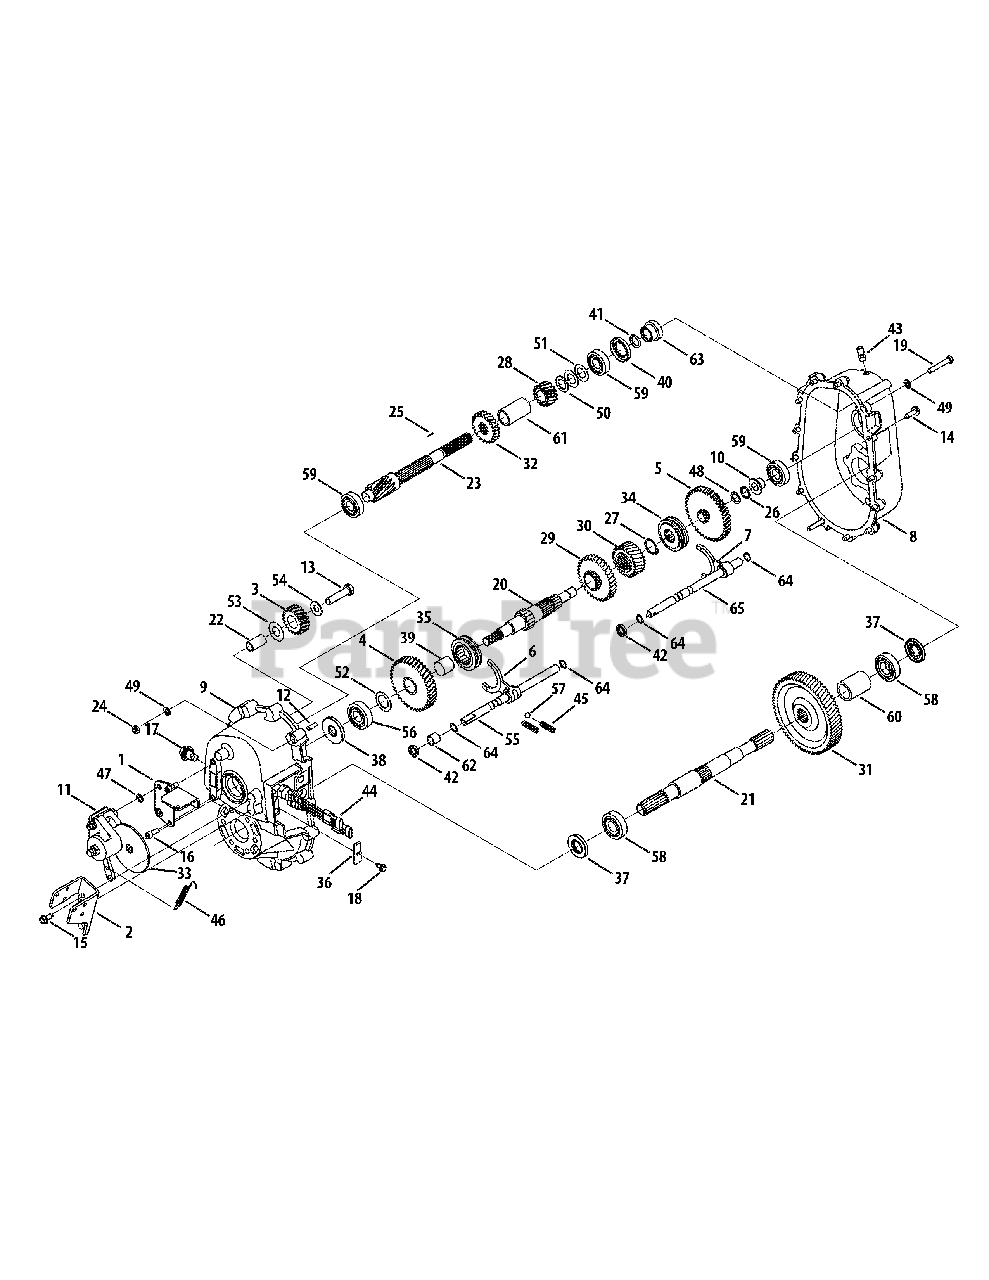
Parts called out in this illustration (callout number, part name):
1	Bracket Assembly, Painted
2	Bracket Assembly, Shift, Painted
3	Gear Assembly, Rev Idler
4	Gear, Rev, 39T
5	Gear Assembly, Low Speed
6	Yoke, Actr, Uv
7	Yoke Actr, Lo
8	Housing, LH, Uv
9	Housing, RH, Uv
10	Spacer, Flg, .630 x .787 x .662
11	Brake Assembly, Transfer Case
12	Dowel, Bush, .400 x .484 x .750
13	Hex Head Screw, 1/2-13, 2.00
14	Screw, Tt, 5/16-18, 1.000, Hxindwsh
15	Screw, Tt, 5/16-18, 0.750, Hxindwsh
16	Screw, Soc Hd, 5/16-18, .750
17	Screw, Plug, M14 x 1.5 x .827
18	Screw, Tt, 1/4-20 x .625, Hxindwsh
19	Hex Head Screw, 5/16-18, 2.00
20	Shaft, Mid, Transfer Case
21	Shaft, Output, Transfer Case
22	Shaft, Rev Idler
23	Shaft, Input, Transfer Case
24	Nut, Hex Lock, 5/16-18, Ctrlk
25	Pin, Roll, 1/8 Od, .63
26	External Snap Ring .625 Dia.
27	Ring, Retainer, 1.125 Dia.
28	Gear, Low Pinion, 15t
29	Gear, High, 33t
30	Gear, Final Pinion, 22t
31	Gear, Final, 73t
32	Gear, Pinion, High, 22t
33	Disc, Brk, Uv
34	Collar, Lo
35	Collar, Hi-rev, 4x4
36	Plate, Detent Spring
37	Seal, Oil, 25x46x7
38	Seal, Oil, 20x52x7
39	Bearing, 25mm x 28mm x 25mm
40	Seal, Oil, 30 x 47 x 7
41	O-ring, .734 Id x .139
42	Seal, Oil, .563 x .875 x .188
43	Creeper Drive Housing Breather
45	Spring, 3/8 Od x 1 1/4 Lg
46	Spring, Extn, .38 Od x 3.9 Lg
47	Washer, Flat, .385 x .620 x .033
48	Washer, Flat, .635x.930x.033, Ht
49	Washer, Flat, .330 x .630 x .0635
50	Washer, Flat, .793 x 1.24 x .06, Ht
51	Washer, Flat, .793x1.368x.010, Ht
52	Washer, Flat, 1.007x1.542x.03, Ht
53	Washer, Thrust, .757 x 1.38 x .062
54	Washer, Flat, .51 x 1.12 x .06, Ht
55	Shaft, Actuator,, Fwd, Rev
56	Bearing, Ball, .79 Id x 2.05 Od x .6
57	Ball, Detent, .375
58	Bearing, Ball, 25x52x15, 6205
59	Bearing, Ball, 20x47x14, 6204
60	Spacer, Output Shaft
61	Spacer, Mid Shaft
61	Spacer, .930 x 1.125 x 3.019
62	Spacer, .566 x .725 x .650
63	Spacer, Input, Uv, Transfer Case
65	Shaft, Actuator, Lo
